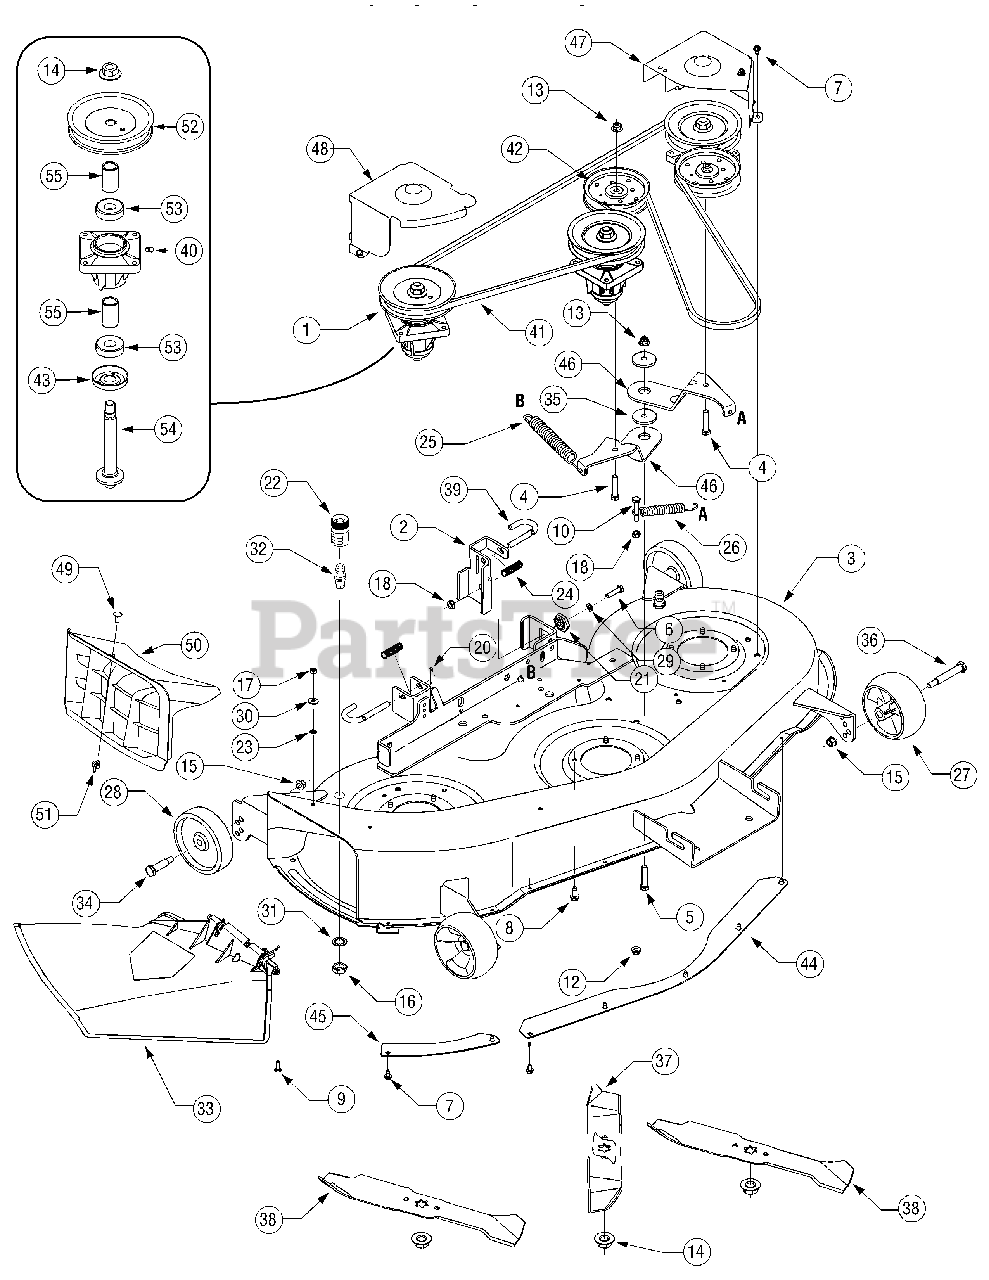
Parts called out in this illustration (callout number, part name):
1	Spindle Assembly, Pulley 5.75 Dia. w/Fitting
4	Screw, 3/8-16, 1.75, Gr5
5	Screw, 3/8-16, 1.50, Gr5
6	Screw, 5/16-18, 1.25, Gr5
7	Screw, 1/4-20, 0.500
8	Screw, 5/16-18, 0.750
9	Screw, 1/4-20, .75, Gr5
10	Screw, 5/16-18, 1.75, Gr5
11	HEX NUT 1/2-13
12	Nut, Flange Lock, 5/16-18, GrF, Nylon
13	Nut, Flange Lock, 3/8-16, GrF, Nylon
15	HEX LOCK NUT
16	Nut, Hex, M16-1.5
18	HEX NUT 5/16-18
19	Nut, Hex Lock, 1/2-13, Gr8, Nylon
20	Pin, Cotter, 3/32, 1.0
21	Adjustment Gear, Deck
22	Coupler, Hose
23	Nut, Push, .25 Id x .50 OD
24	Spring, Compression, .531 OD x 1.75
25	Spring, Extension, .91 Dia. x 7.33
26	Spring, Extension, .865 OD x 4.68
27	Wheel, Deck, 5.0, Ball
28	PLASTIC WHEEL 5X1.38
29	Washer, Lock, 5/16, Regular Duty
30	SPRING WASHER BELL
31	Washer, Lock, 17 x 23.8 x 1.95
32	Port, Water
33	Chute Assembly, Side Discharge
34	Screw, Shoulder, .498 x 1.53, 3/8-16
35	Spacer, Shoulder, .8840 x .190
36	Screw, Shoulder, 1/2 Dia x 2.50
37	Blade, 14.88", Star 3-in-1
38	Blade, 16.28", Star 3-in-1
39	Handle Rod, Deck Release .375 Dia
40	GREASE FITTING
41	Belt, V-Type
42	Pulley, Idler, 4.25"Dia.
43	Bearing Shield
46	Bracket, Idler Replaces 783-05002
50	Mulch Plug
51	WING NUT 1/4-20
52	Pulley, 5.75 Dia.
53	Ball Bearing, .787 x 1.85 x .551
54	Shaft, Spindle, 6.11 Lg
55	Spacer, 1.8
